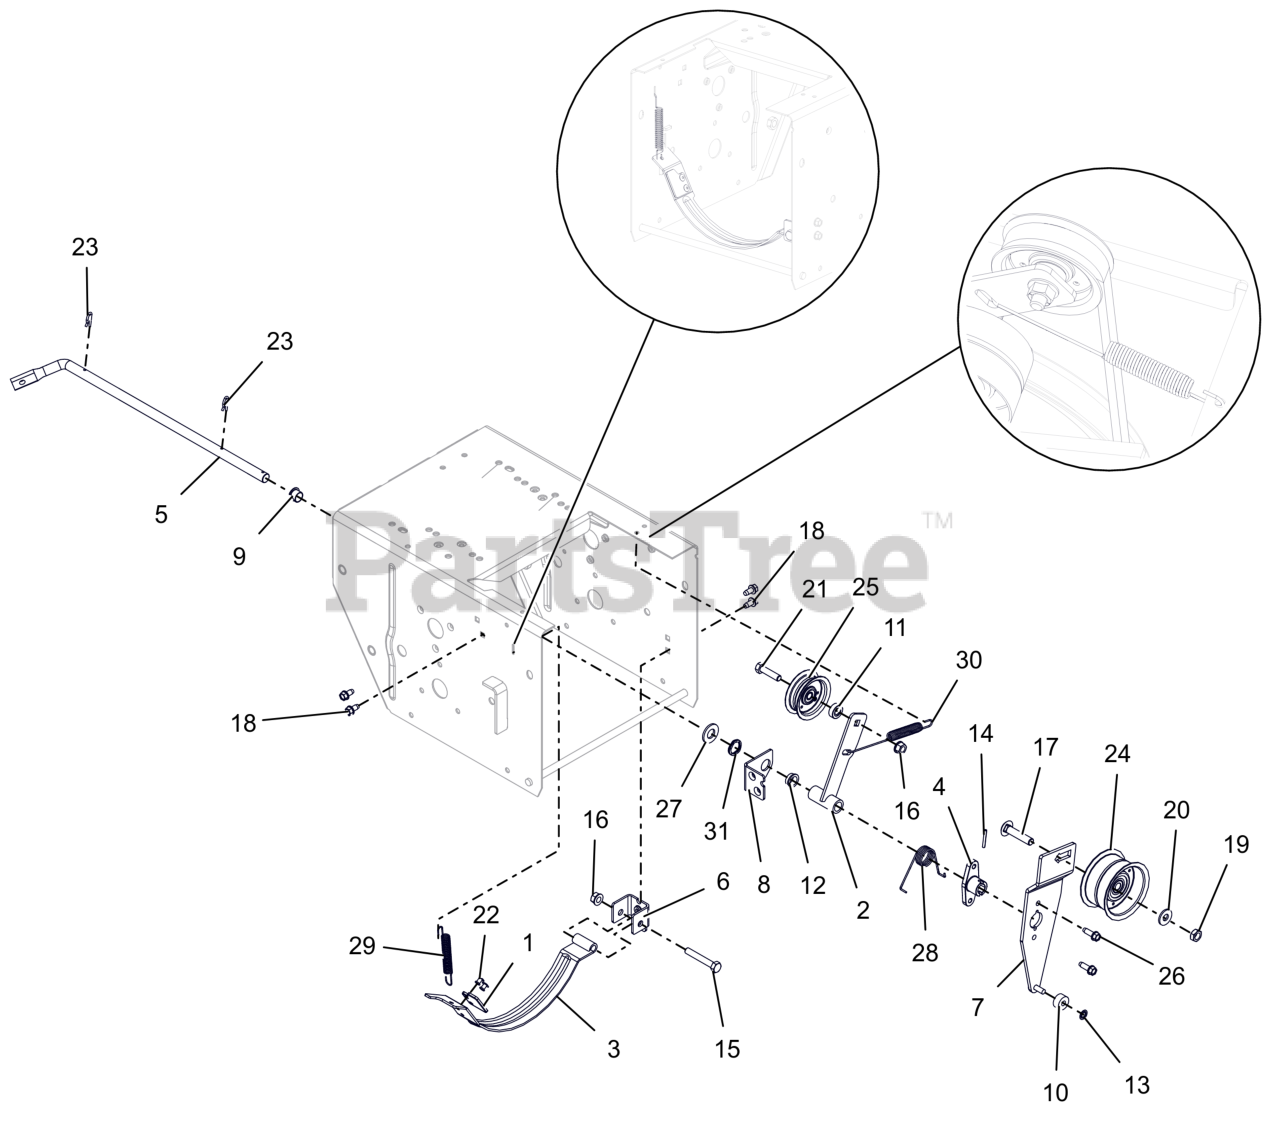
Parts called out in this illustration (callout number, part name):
1	PAD, BRAKE
2	ARM, IDLER-TRACTION
3	ARM, BRAKE-ATTACHMENT
4	HUB, BRAKE ARM
5	ARM, ATTACHMENT
6	PIVOT, BRAKE
7	ARM, IDLER - ATTACHMENT
8	BRACKET, SUPPORT
9	BUSHING, POLYLINER-.50 SPLIT
10	BSHG,SLV .265 X .625 X .375
11	SPCR, BRG .315X.500X.358X.281
12	BSHG,FLANGE .500X.625X.270X.75
13	RG-RTNG-EXT .250X.010
14	PIN-ROLL .125X1.00
15	BLT, HEX .31-18X2.00 G5 ZCC
16	NUT-LK-TOP-FLG .312-18 GF ZCC
17	BLT, RHSSN .38-16X1.75 G5 ZCC
18	SCR-TAP .25-20X.50 HWH ZCC
19	NUT-LK-CTR-JAM .375-16 GB ZCC
20	WSHR,FLT .375X.875X.083 ZCC
21	BLT, HEX .31-18X1.25 G5 ZCC
22	RVT, POP .1875 ZCC
23	CLIP, SPRING
24	IDLER, FLANGE -2.75 OD X .375 ID
25	IDLER, FLAT - 2.00"
26	SCR,TAP .25-20X.75 HWH TR ZCC
27	WSHR,FLT .531X1.062X.095 ZCC
28	SG-TORS .067X.88
29	SPRING-EXT .437 X .438 X 2.64
30	SG-TENS .06X.482X5.35
31	WAVE SPRING .600X.875X.25FH
